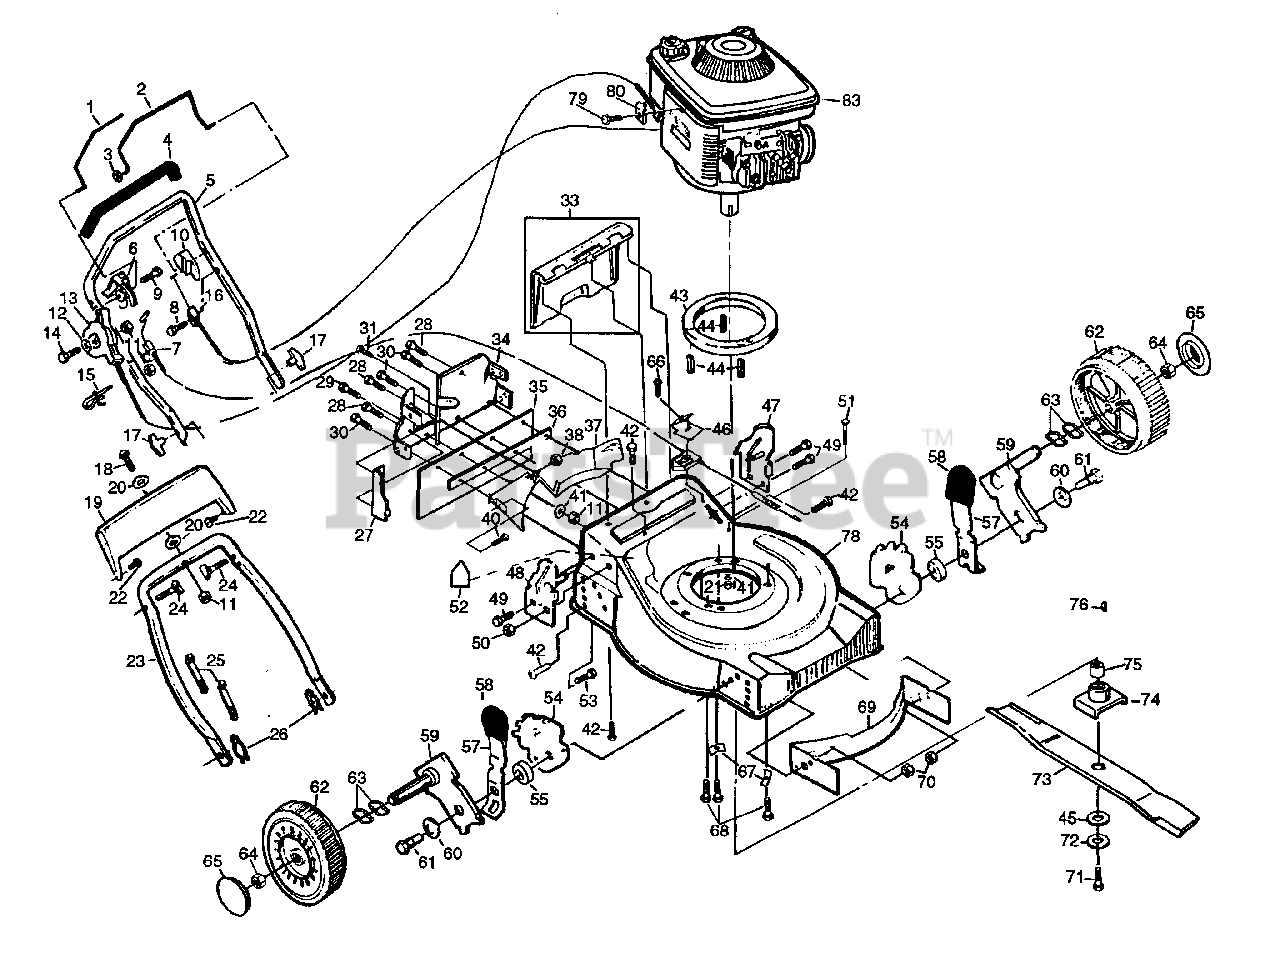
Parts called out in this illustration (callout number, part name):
1	Drive Bar
2	Engine Control Bar
3	Flat Washer
4	Handle Grip
5	Upper Handle
6	Drive Control Actuator
7	Drive Cable Assembly
8	Thread Rolling Screw #10-24 x 3/4
9	Self-taping Screw #10-24 x 5/8
10	Zone Control Actuator
11	Locknut 1/4-20
13	Throttle Control
14	Machine Screw 1/4-20 x 2-1/8
15	Rope Guide
16	Engine Zone Control Cable
17	Handle Knob
18	Hex Washer Head Machine 1/4-20 x 1-1/2
19	Trim Plate
20	Flat Washer 1/4
21	Locknut 1/4-20
22	Self-tapping Screw #10-24 x 5/8
23	Lower Handle
24	Handle Bolt 5/16-18 x 1-3/4
25	Wire Ties
26	Hairpin Cotter
27	Side Baffle
28	Self-tapping Screw #10-24 x 3/8
29	Hex Head crew 1/4-20 x 3/4
30	Hex Tapping Screw 1/4-20 x 1/2
31	Hex Washer Head Machine Screw #10-24 x 9/16
33	Rear Door Kit
34	Back Plate
35	Rear Skirt
36	Backing Strip
37	Rear Baffle
40	Hex Washer Head Tapping Screw #10-24 x 1/2
42	Hex Tapping Screw 1/4-20 x 1/2
43	Engine Spacer
44	Engine Bushing
46	Bracket Cover
47	Handle Bracket Assembly (Left)
48	Handle Bracket Assembly (Right)
49	Thread Cutting Screw 5/16-18 x 3/4
50	Locknut 5/16-18
51	Carriage Bolt 1/4-20 x 1/2
52	Danger Decal
53	Carriage Bolt 5/16-18 x 5/8
54	Wheel Adjusting Bracket
55	Spacer
57	Selector Spring
58	Selector Knob
59	Axle Arm Assembly
60	Belleville Washer
61	Shoulder Bolt 3/8-16
62	Wheel & Tire Assembly 8.0 x 2.0
63	Washer
64	Locknut
66	Screw, Self Tap 10-24 x 3/4
67	Engine Washer
68	Hex Head Thread Rolling Screw 3/8-16 x 2
69	Front Baffle
70	Locknut 3/8-16
71	Hex Head Machine Screw Gr. 8
72	Helical Washer 3/8
74	Blade Adapter
76	Hi-Pro Key #HP-505
78	Lawn Mower Housing
79	Thread Rolling Screw #10-32 x 5/8
80	Cable Clamp
83	Engine
